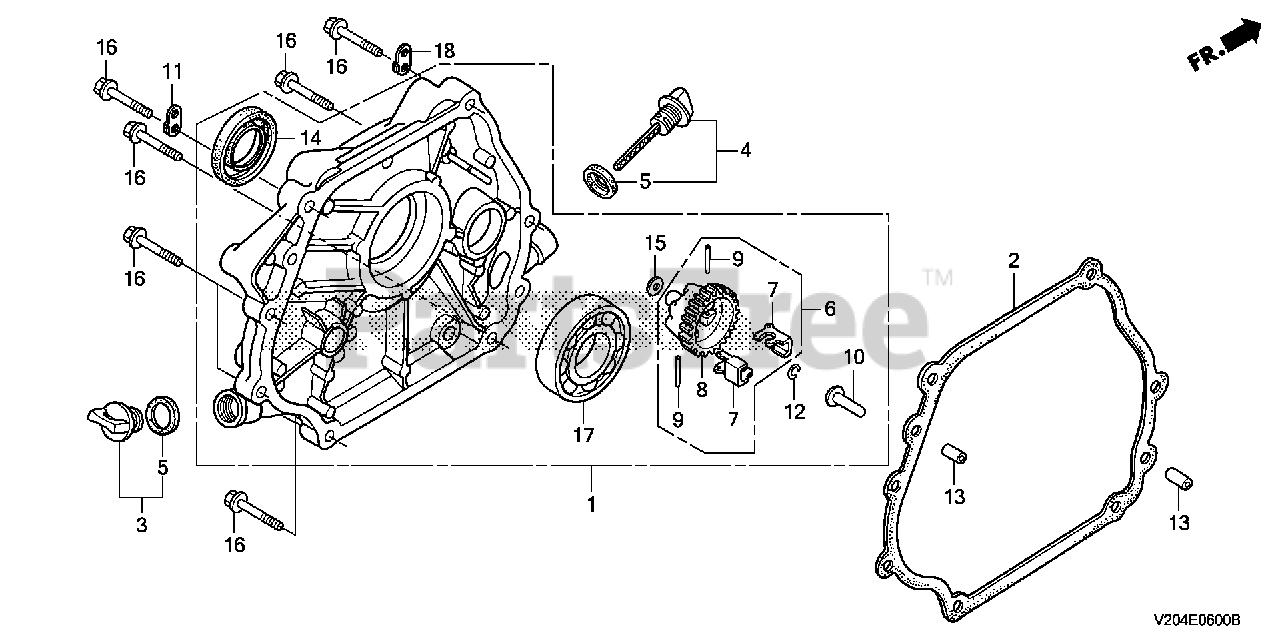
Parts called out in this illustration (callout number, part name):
1	COVER ASSY., CRANKCASE
2	GASKET, CASE COVER
3	CAP ASSY., OIL FILLER (BLACK)
4	CAP ASSY., OIL FILLER
5	GASKET, OIL FILLER CAP
6	GOVERNOR ASSY.
7	WEIGHT, GOVERNOR
8	HOLDER, GOVERNOR WEIGHT
9	PIN, GOVERNOR WEIGHT
10	SLIDER, GOVERNOR
12	CLIP, GOVERNOR HOLDER
13	PIN, DOWEL (8X12)
14	OIL SEAL (30X46X8) (NOK ASIA)
15	WASHER, PLAIN (6MM)
16	BOLT, FLANGE (8X35)
17	BEARING, RADIAL BALL (6206)
18	STAY, WIRE CLIP (A)
